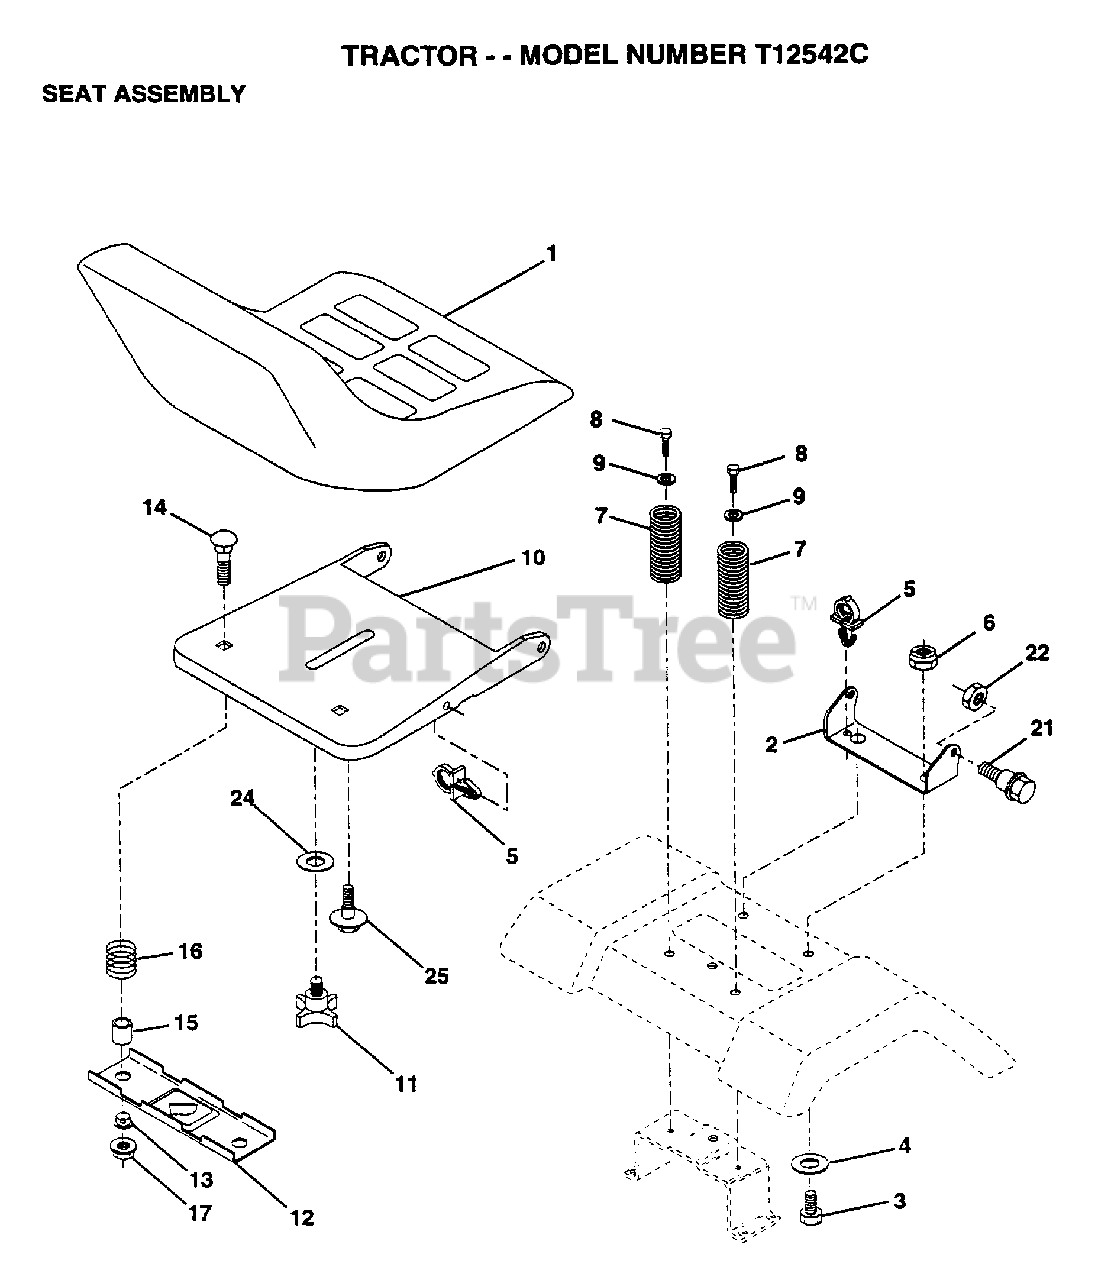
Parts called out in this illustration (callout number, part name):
2	BRACKET PVT SEAT
3	BOLT
4	WASHER PM
5	CLIP.PUSH-IN.HING
6	NUT
7	SPRING COMPRESSIO
8	SCREW GTV
9	WASHER
11	"KNOB 1/2"" YT"
12	BRKT SWITCH
13	BUSHING
15	SPACER SPLIT
16	SPRING COMPRESSED
21	BOLT.SHLD.5/16-18
24	WASHER
25	"BOLT,SHOULDER"
